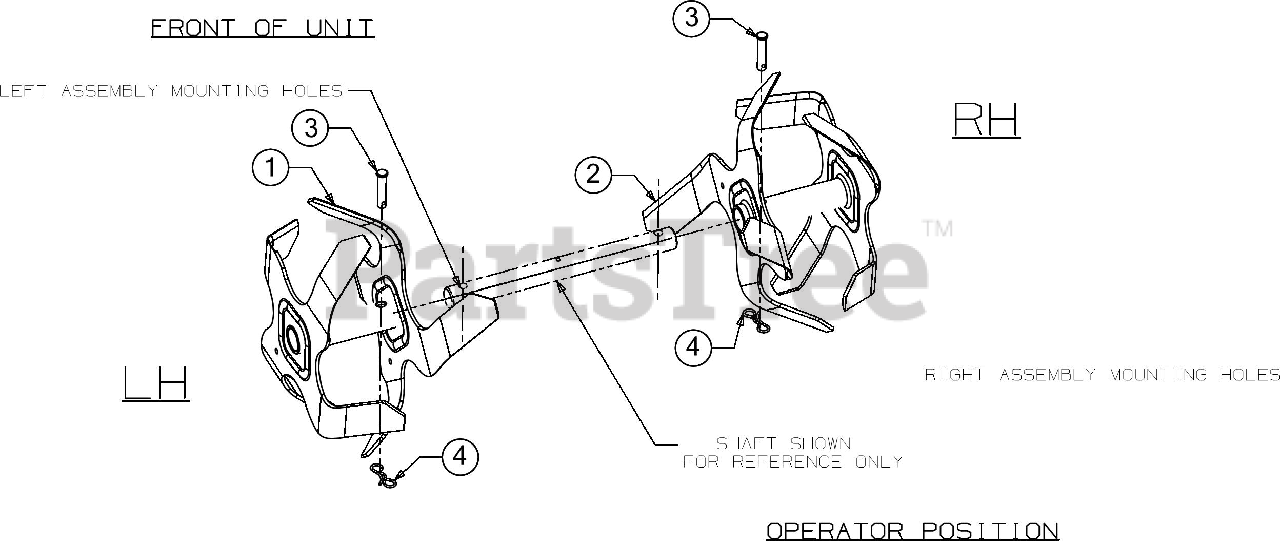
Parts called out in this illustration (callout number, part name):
1	TINE ASSEMBLY (LH)
2	TINE ASSEMBLY (RH)
3	CLEVIS PIN .375 X .1.75
4	PIN:COTTER
